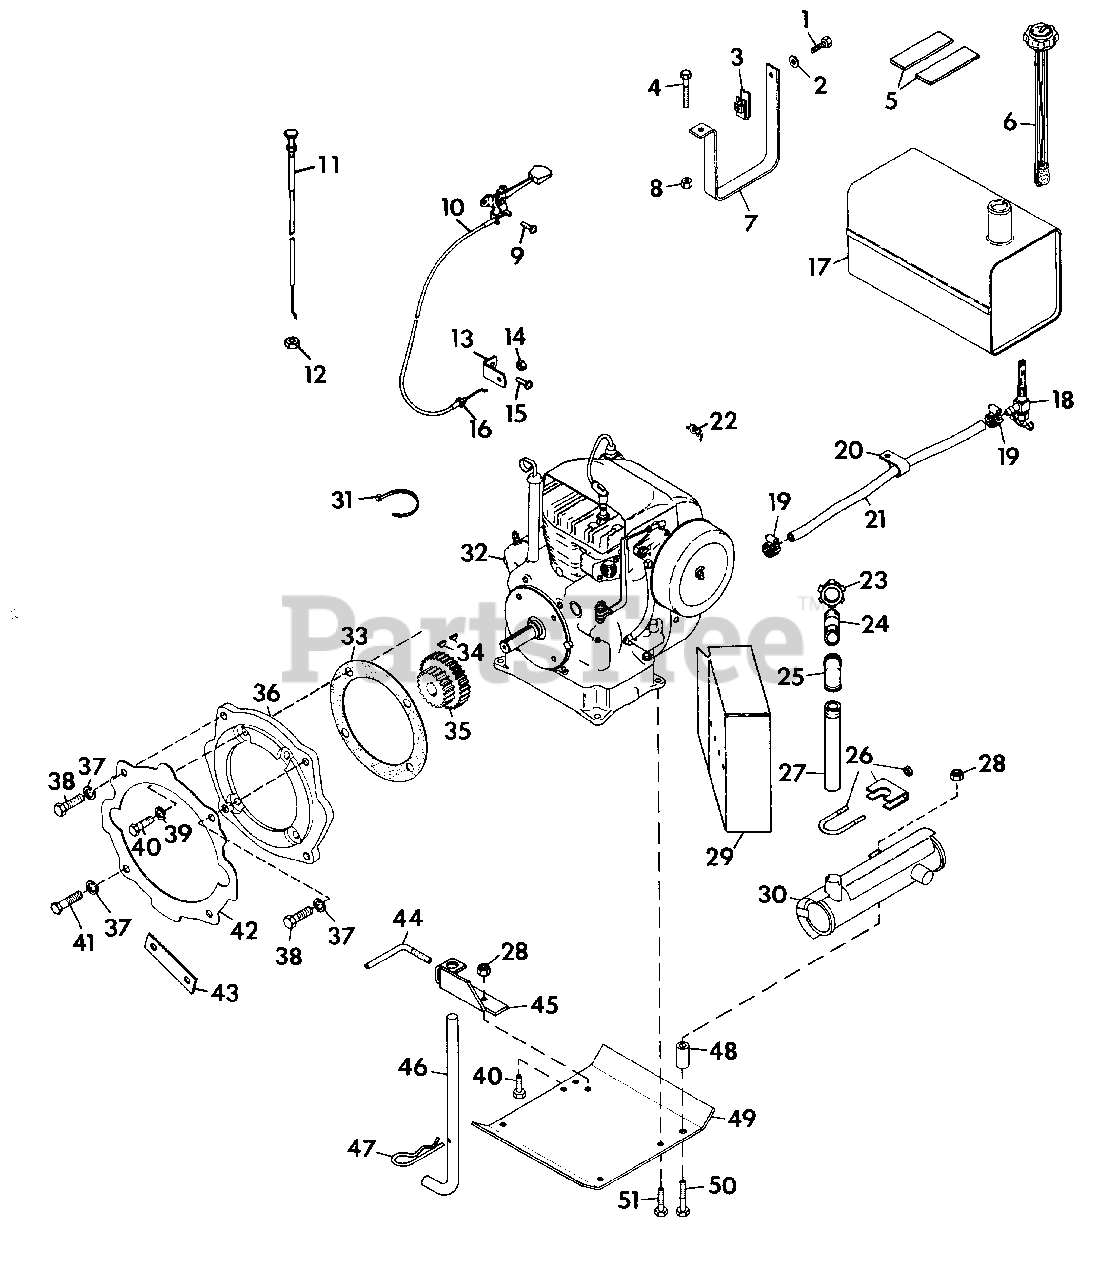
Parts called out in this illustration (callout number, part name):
1	BOLT, HEX 5/16-18X.75
2	WASHER, FLAT .343X.688X.065
3	NUT, RETAINER
4	BOLT, HEX 5/16-18X1.25
5	PAD, GAS TANK
6	GAUGE, FUEL
7	STRAP, GAS TANK
8	NUT, LOCK 5/16-18
9	SCREW, TAPPING 1/4-20X.50
10	LEVER, CONTROL
11	CONTROL, CHOKE
12	NUT, JAM 3/8-24 HEX
13	BRACKET
14	NUT, HEX 1/4-20
15	SCREW, MACH. 1/4-20X.50
16	ADAPTOR, CONDUIT
17	TANK, FUEL
18	VALVE AND STRAINER
19	CLAMP, HOSE
20	CLAMP, NYLON
21	LINE, FUEL
22	CLIP, SPEED
23	NUT, CONDUIT 1.25" PIPE
24	NIPPLE, 1.25 PIPE
25	ELBOW, 1.25 PIPE
26	CLAMP, MUFFLER
27	NIPPLE, 1.25 PIPE 7.8 LG.
28	NUT, LOCK 3/8-16
29	SHIELD, HEAT
30	MUFFLER, KOHLER 16-HP
31	TIE, CABLE
32	ENGINE, 16-HP KOHLER
33	GASKET, ENGINE TO ADAPTOR
34	KEY, WOODRUFF 5/32X.625
35	GEAR, 10/12 DP 21/30 TEETH
36	ADAPTOR, ENGINE
37	WASHER, LOCK 7/16 SP HEAVY
38	BOLT, HEX 7/16-14X1.50
39	WASHER, LOCK 3/8 SP HEAVY
40	BOLT, HEX 3/8-16X1.00
41	BOLT, HEX 7/16-14X1.25
42	GASKET, CHASSIS TO ADAPTOR
43	STRAP
44	HANDLE, ADJUSTING
45	STAND, SUPPORT
46	STAND, KICK
47	PIN, HAIR
48	BUSHING, .407X.625X.812
49	PLATE, SKID
50	BOLT, HEX 3/8-16X1.75
51	BOLT, HEX 3/8-16X1.50
